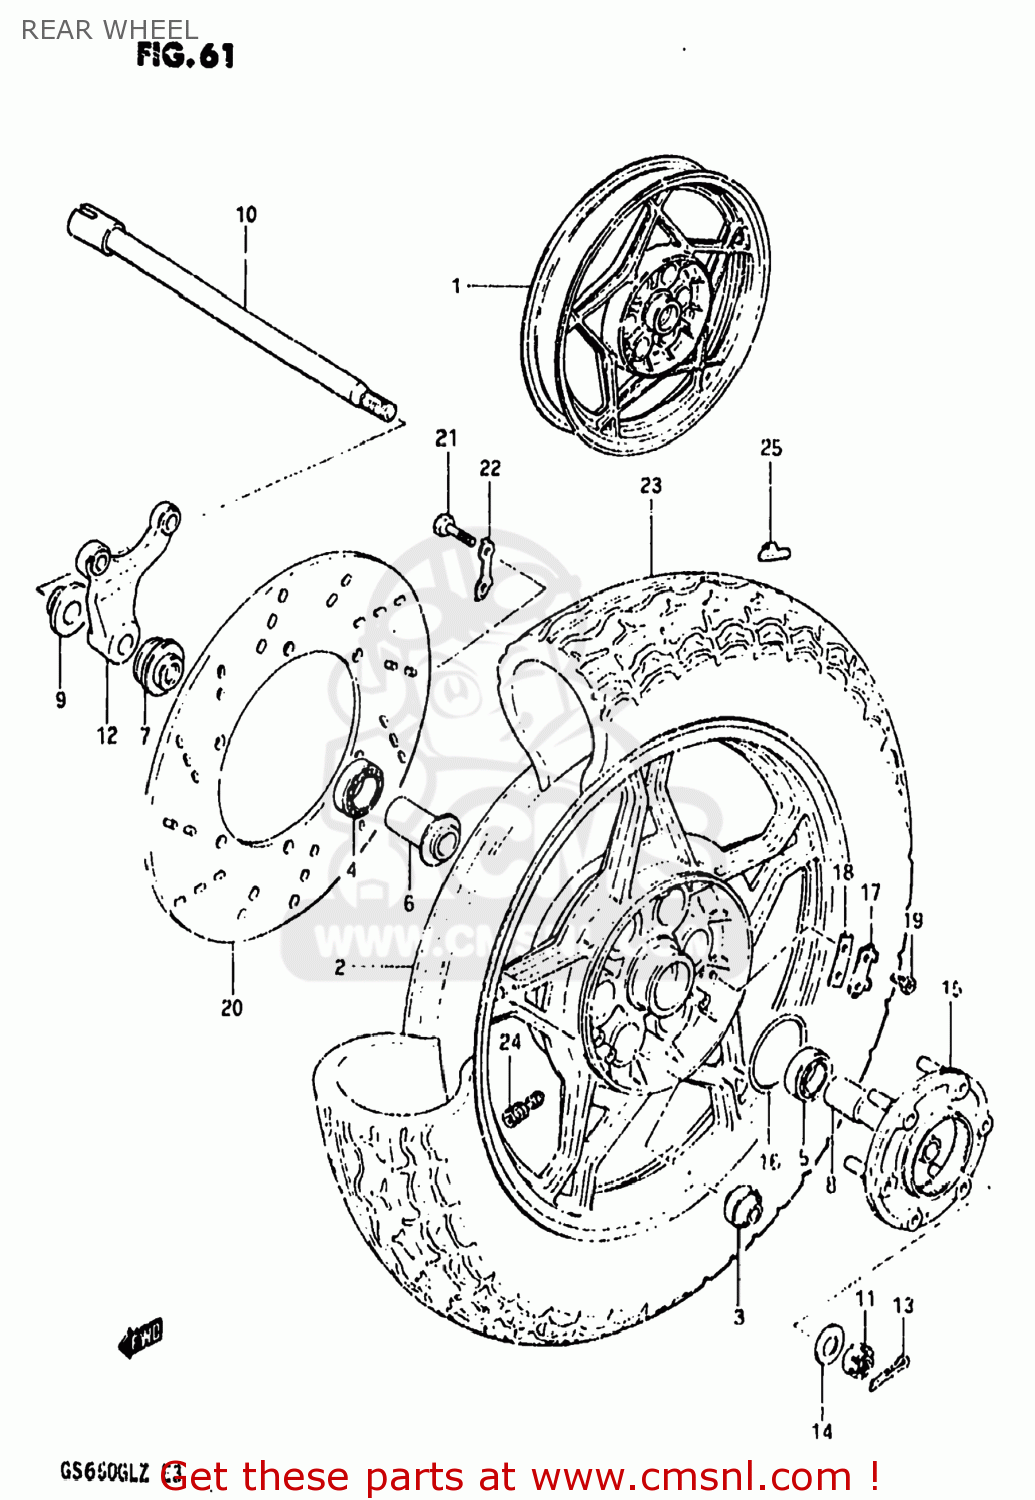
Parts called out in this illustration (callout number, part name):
1	WHEEL SET,REAR
2	CASTING WHEEL,REAR
3	BUSH
4	BEARING
5	BEARING
6	SPACER,REAR HUB BEARING
7	SPACER,REAR AXLE
8	SPACER,REAR AXLE,LEFT
9	SPACER,REAR AXLE,RIGHT
10	AXLE,REAR
11	NUT
12	BRACKET,RR,CALIPER
13	PIN,COTTER
14	WASHER(16.5X36X3.2)
15	JOINT ASSEMBLY,REAR HUB DRUM
16	O RING(D:2.1,ID:65)
17	WASHER
18	WASHER,THRUST(T:1.6)
19	SCREW
20	DISC,RR BRAKE
21	BOLT(8X25)
22	WASHER
23	TIRE
24	VALVE ASSEMBLY,WHEEL RIM,J
25	BALANCER,WHEEL
